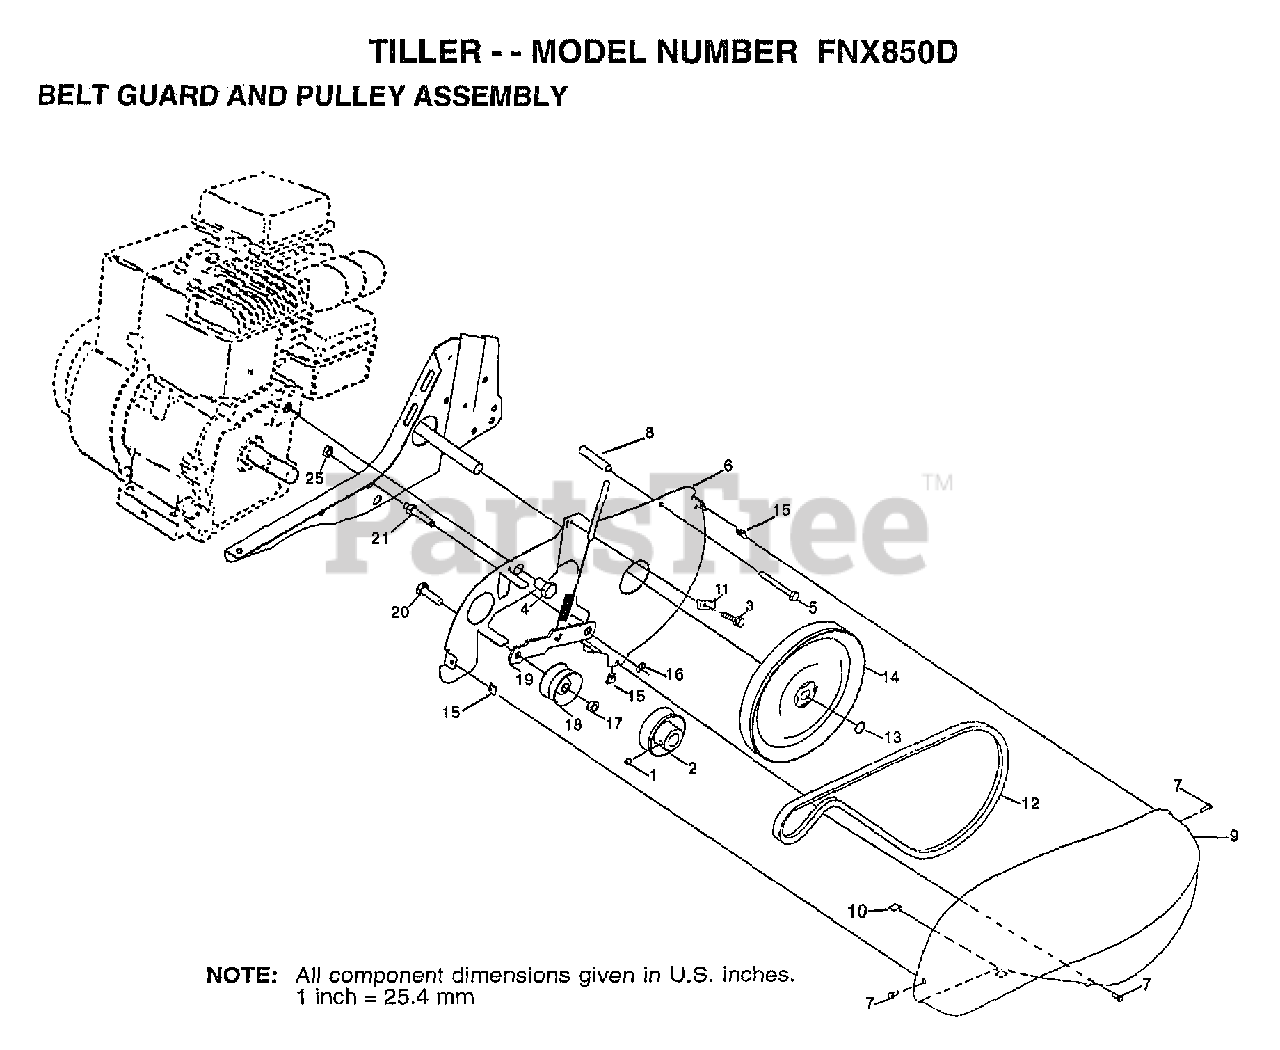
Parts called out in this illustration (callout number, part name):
1	SET SCREW
2	ENGINE PULLEY
3	SCREW.HEX.WSH.
4	BOLT.HEX.HEAD
5	BOLT.ROLLER.1/4-20X2 1/2
6	SHEILD.INNER.GUARD
7	SCREW HX WSH.HD#8-18X1/2
8	SPACER.SPLIT
9	GUARD.PNT.BELT
10	PAD IDLER TI
11	CONDIUT CLIP T
12	V BELT STD
14	LEVR ASM CLUTCH
15	NUT J CLIP #8
16	KLIP RING TI
17	NUT
18	"PULLEY,IDLER"
19	"ARM, IDLER"
21	SHAFT IDLER TI
25	JAM NUT TI
